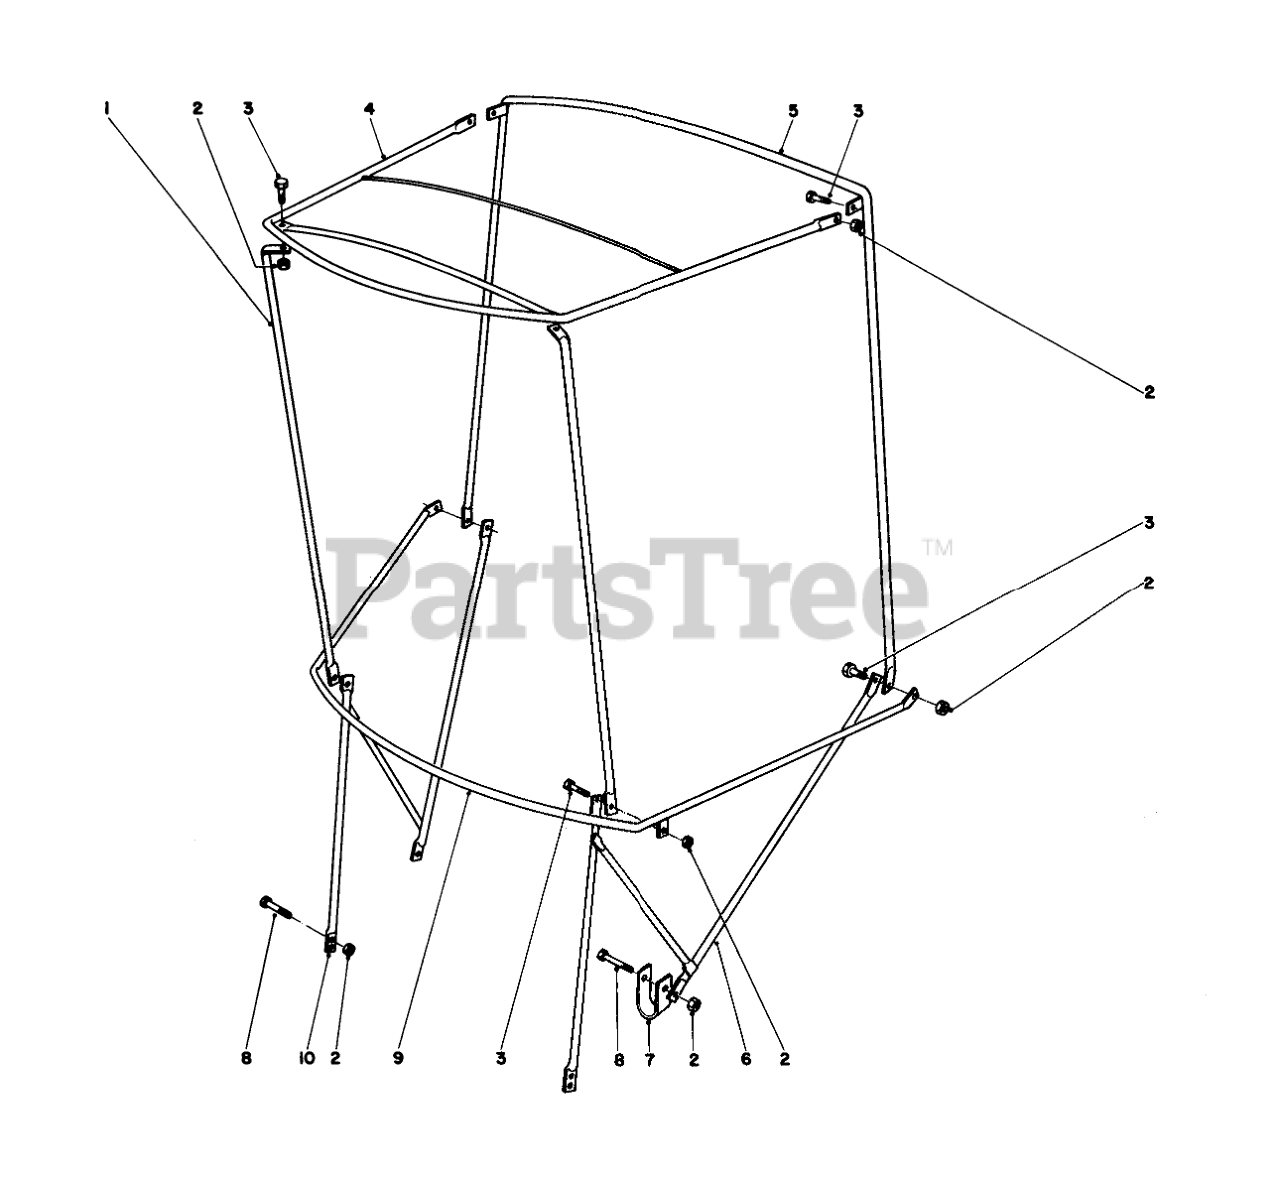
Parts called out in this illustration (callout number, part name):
2	NUT-LOCK, NI
3	SCREW-HH
4	FRAME-TOP
5	BOW-VERTICAL, REAR
6	ATTACHING BRKT L
7	U CLAMP
8	SCREW-HH
9	BOW-CURVED
10	ATTACHING BRKT R
